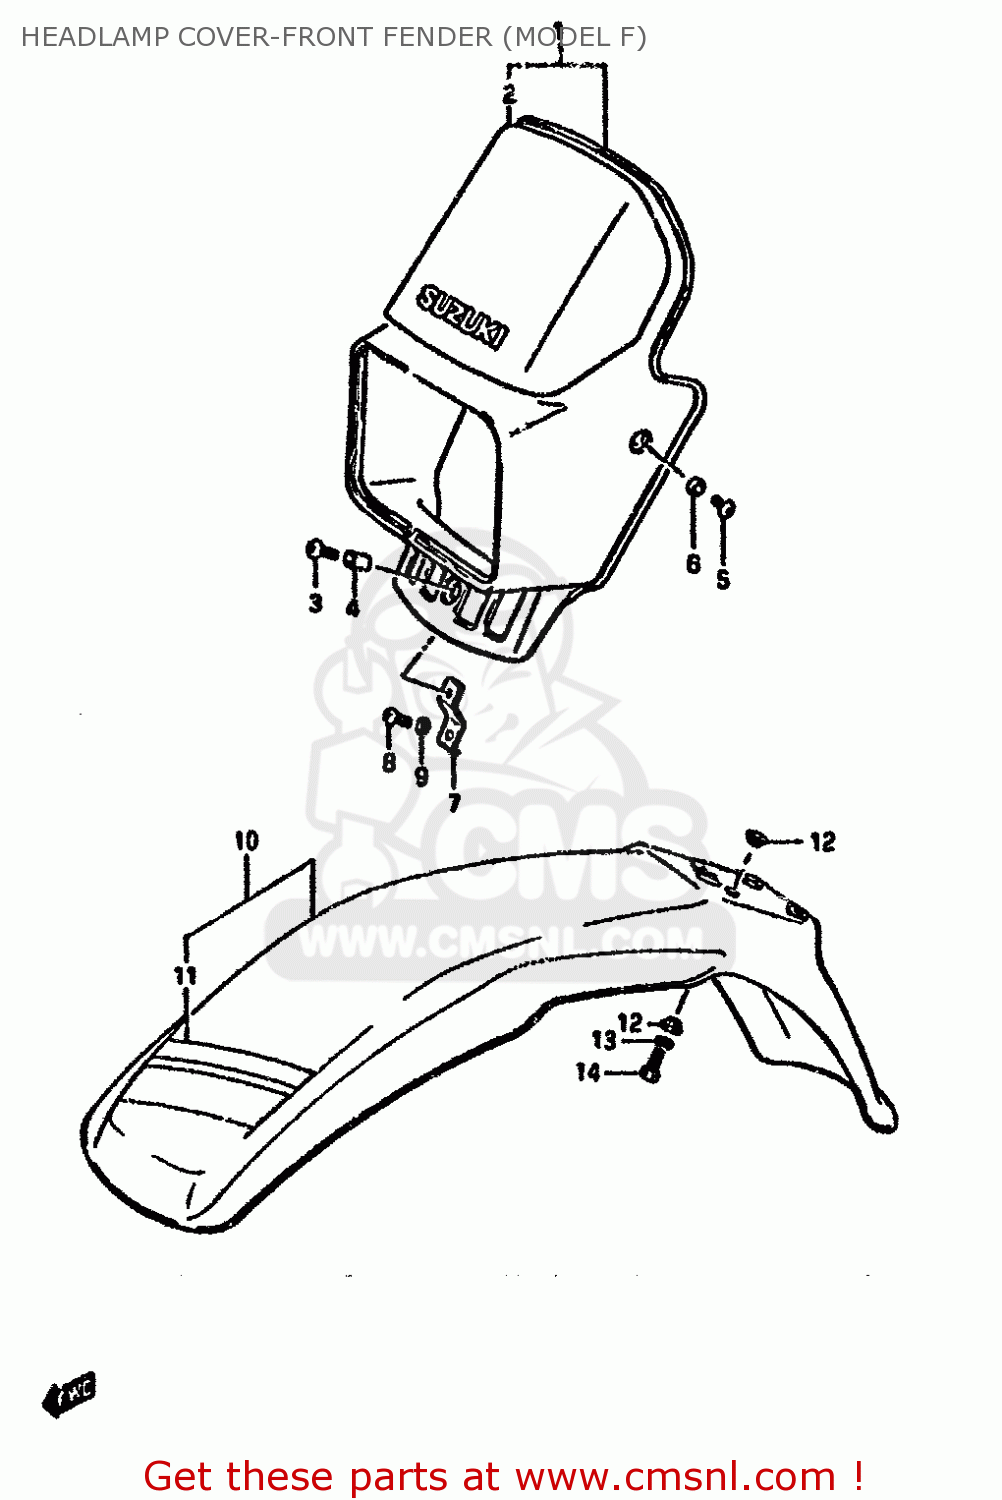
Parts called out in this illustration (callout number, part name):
1	COVER,HEADLAMP
2	TAPE SET
3	SCREW, CENTER
4	SPACER (6.1X8X12)
5	SCREW 6X12
6	SPACER (6.1X8X3.5)
7	BRACE,HEADLAMP HOUSING LWR
8	SCREW 6X12
9	WASHER,LOCK
10	FENDER,FRONT
11	TAPE SET
12	WASHER
13	WASHER,LOCK
14	BOLT
